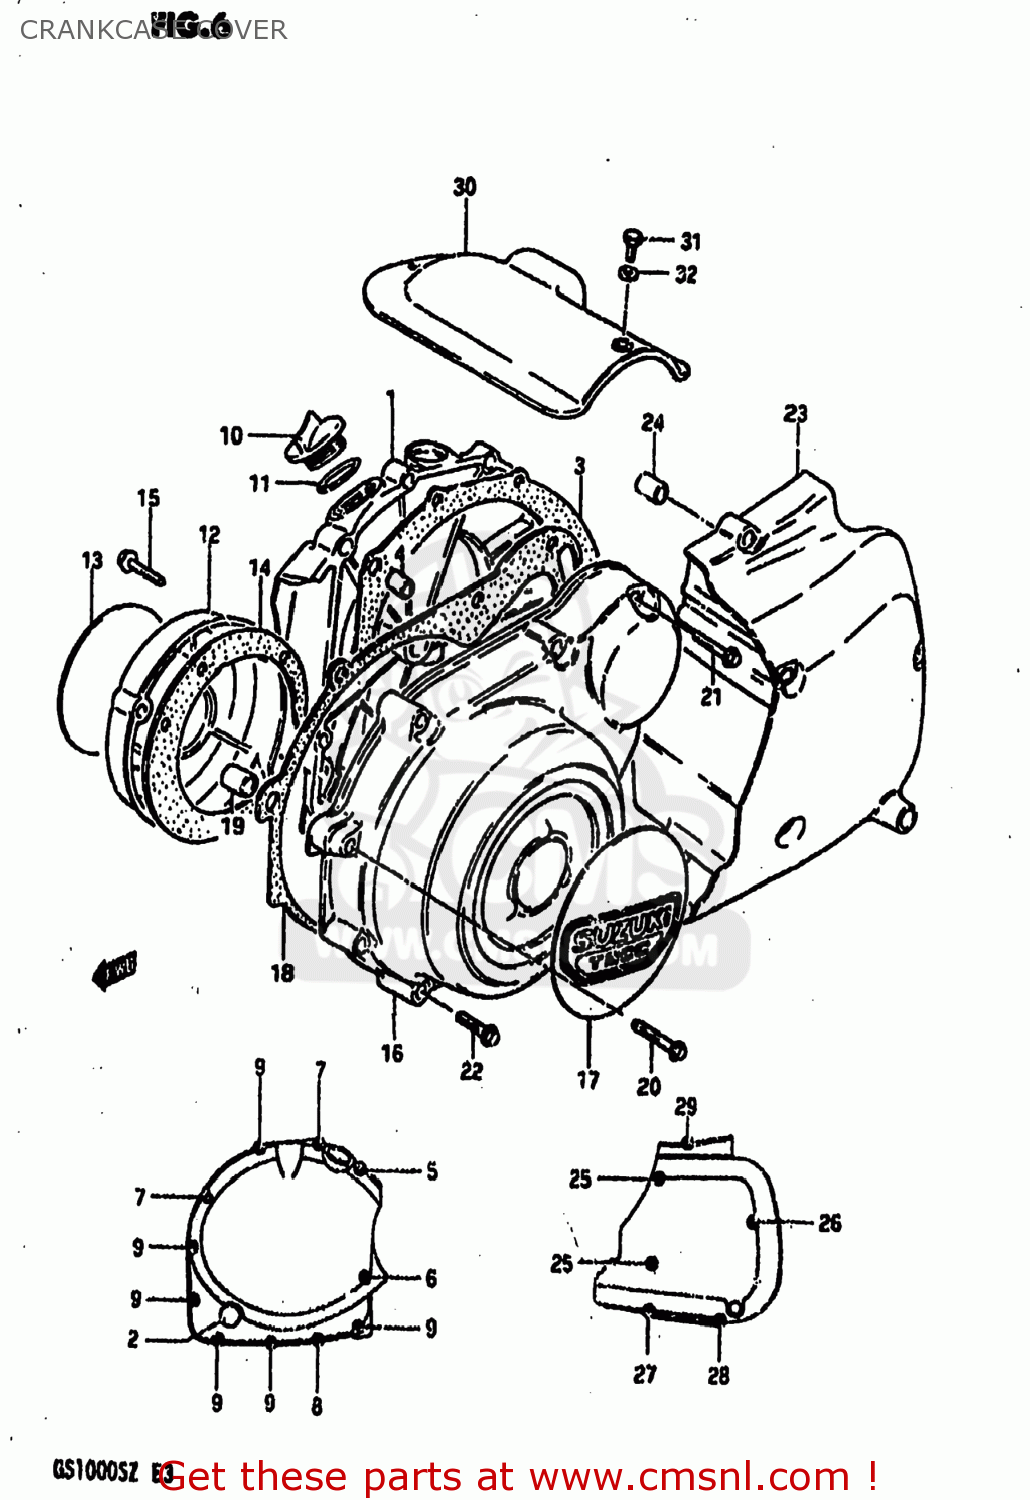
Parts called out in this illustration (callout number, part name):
1	COVER,CLUTCH
2	LENS,OIL LEVEL CHECK
3	GASKET,CLUTCH COVER (MCA)
4	PIN
5	BOLT (6X40)
6	BOLT (6X35)
7	BOLT (6X30)
8	BOLT
9	BOLT (6X20)
10	CAP
11	O RING(D:2.2,ID:32)
12	COVER,CONTACT BREAKER
13	EMBLEM
14	GASKET,CONTACT BREAKER COVER (NAS)
15	BOLT (5*30)
16	COVER,MAGNETO
17	EMBLEM,MAGNETO COVER
18	GASKET,MAGNETO COVER (MCA)
19	PIN
20	BOLT
21	BOLT (6X40)
22	BOLT (6X35)
23	COVER,ENGINE SPROCKET
24	PIN
25	BOLT 6X95
26	BOLT (6X85)
27	BOLT (6X70)
28	BOLT (6X55)
29	BOLT (6X30)
30	COVER,STARTER MOTOR
31	BOLT
32	WASHER
